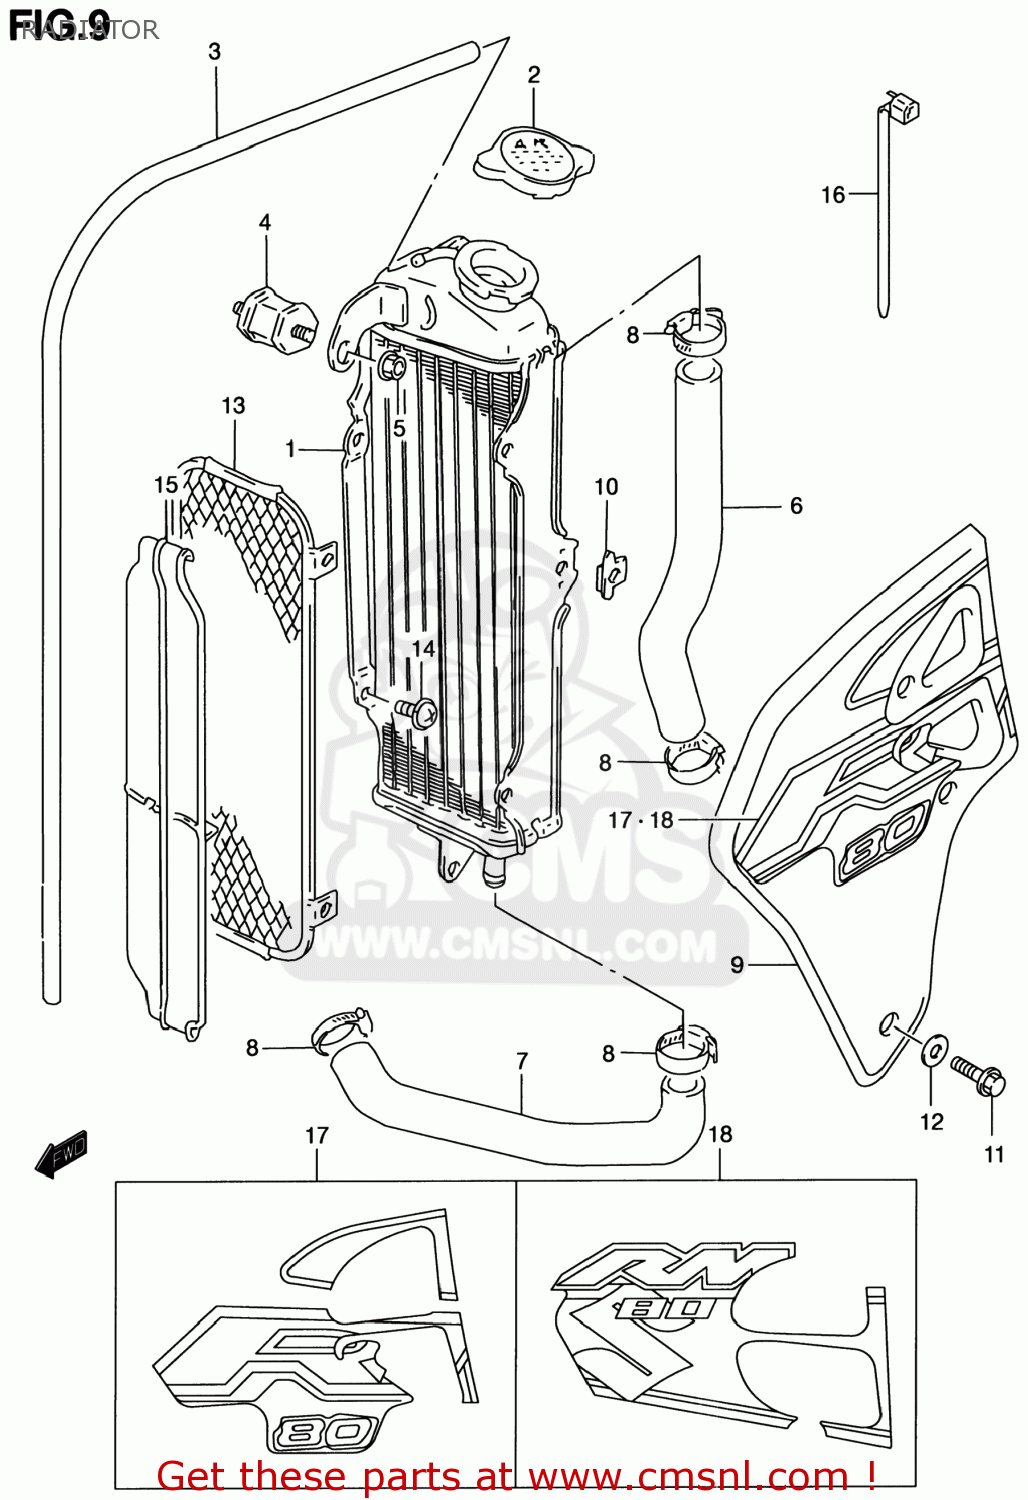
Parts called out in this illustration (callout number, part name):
1	RADIATOR ASSY,WATER
2	CAP COMP,RADIATOR
3	HOSE(5X8X1000)
4	BOLT,RADIATOR CUSHION
5	NUT
6	HOSE,RADIATOR INLET
7	HOSE,RADIATOR OUTLET
8	CLAMP
9	COVER,RADIATOR
10	PLATE,RADIATOR COVER FITING
11	BOLT
12	WASHER(6.5X18X1)
13	BUMPER,RADIATOR
14	SCREW
15	COVER,RADIATOR
16	CLAMP(L:235)
17	TAPE SET,RADIATOR COVER
18	TAPE SET,RADIATOR COVER
